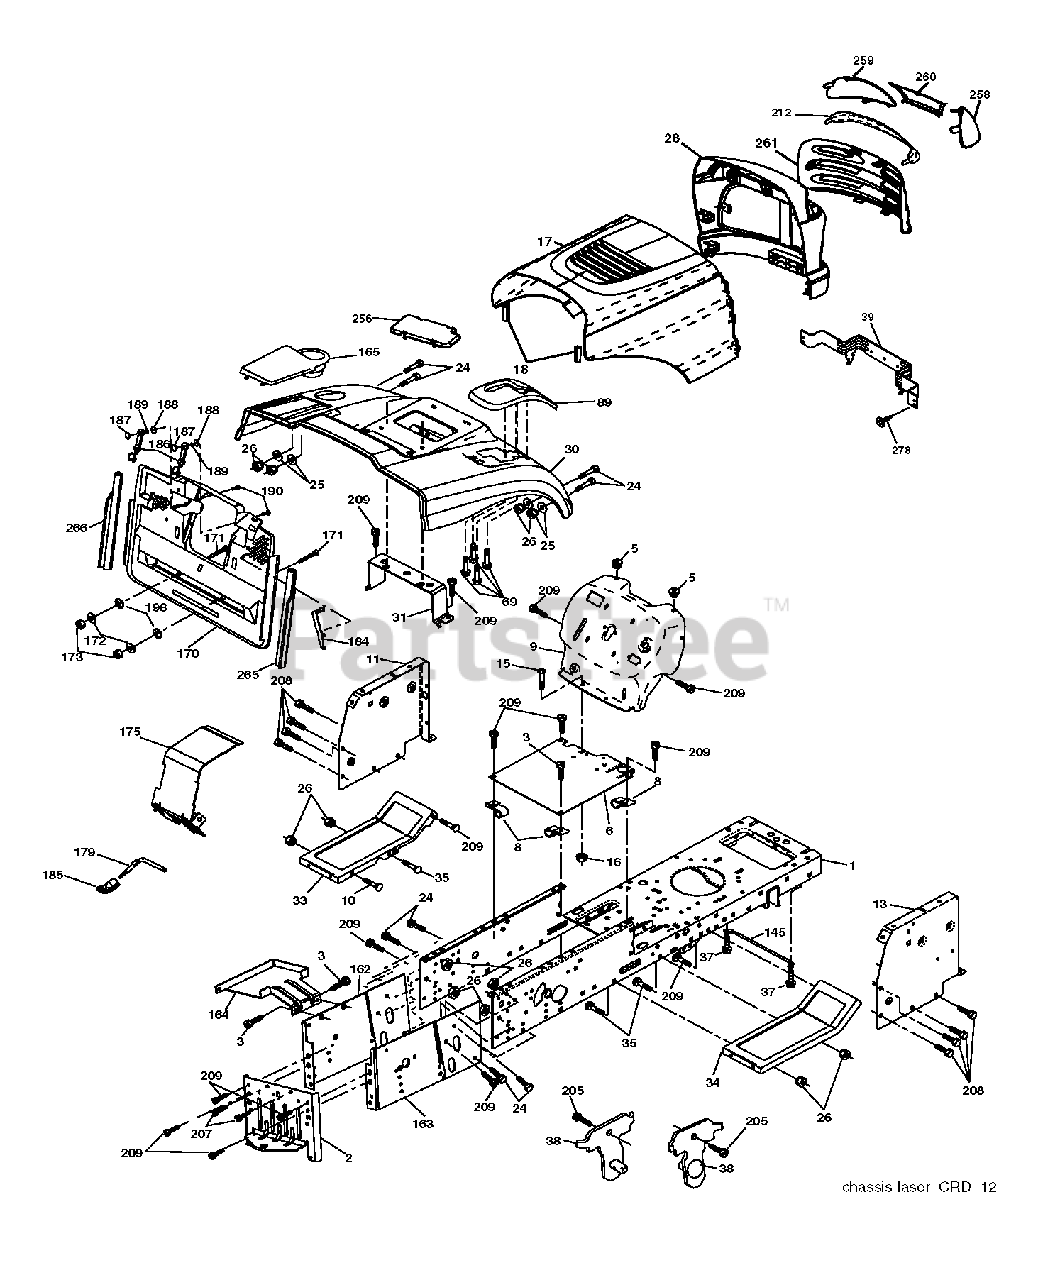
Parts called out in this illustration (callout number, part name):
1	CHASSIS
3	SCREW 3/8-16X3/4
5	BUMPER.RUBBER.HOOD
8	CLIP,INSULATOR
9	FENDER LT SH
10	BOLT D
11	PANEL.DASH.LH.LTX
13	PANEL DASH RH
16	NUT
18	BUMPER.HOOD.LARGE.1.75"
25	WASHER
26	NUT
28	GRILLE.LASER II.DUAL.
30	FENDER.PNT.CRD.MS428 K
31	BRACKET SUPPORT FENDER
33	FOOTREST - LH
34	FOOTREST, RH
39	BRACKET PIVOT
69	SCREW.HI-LO.CONSOLE
145	ROD.PIVOT.HOOD
164	SUPPORT
165	FENDER.PNT.CRD.
171	BOLT
172	WASHER
184	BRACKET.ACTUATOR.BAGGER.SRD
187	WELDNUT
207	SCREW, 5/16-18 X 1/2
208	SCREW 3/8-16X1/2
209	SCREW, 3/8-16X3/4
256	FENDER.PNT.CRD
258	LENS.LASER.2PC.LH.CLEAR.SVC
259	COVER.LENS.LASER.II
278	SCREW.#10 X 0.750.BOS THREAD
